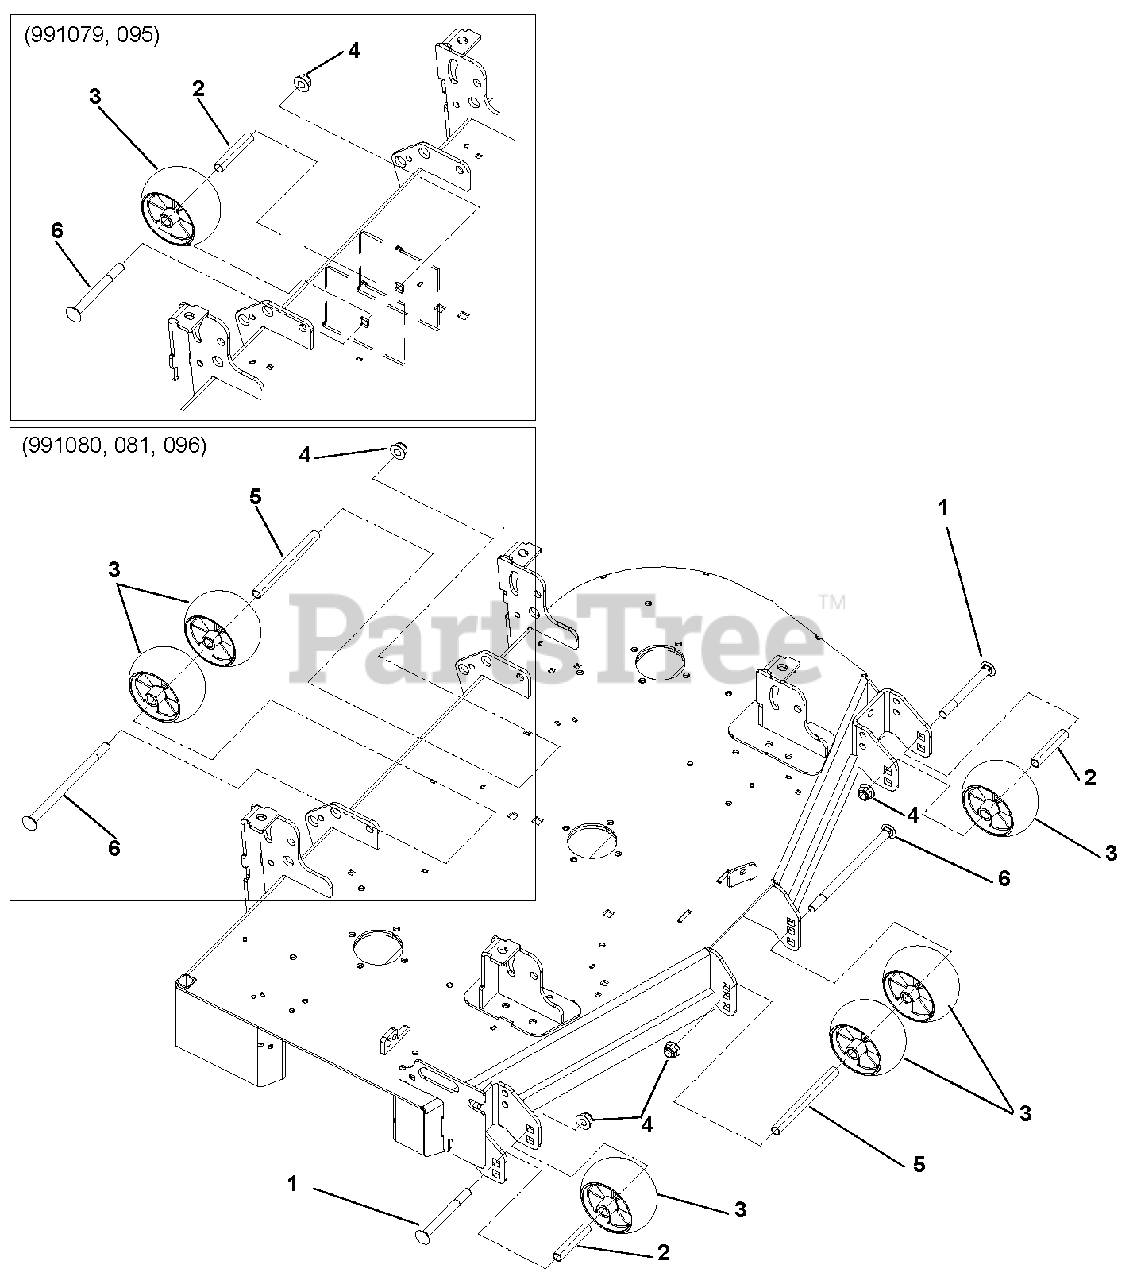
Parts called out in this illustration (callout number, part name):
1	Bolt, Round Head Square Neck .50-13 x 5.00 (991079, 095)
2	Spacer, .510 x .625 x 3.35 (991079, 095)
3	Anti-Scalp Wheel (991079, 095)
4	Nut, .50-13 Nyloc Flange
5	Spacer, .510 x .625 x 6.70 (991079, 095)
6	Bolt, Round Head Square Neck .50-13 x 8.50 (991079, 095)
